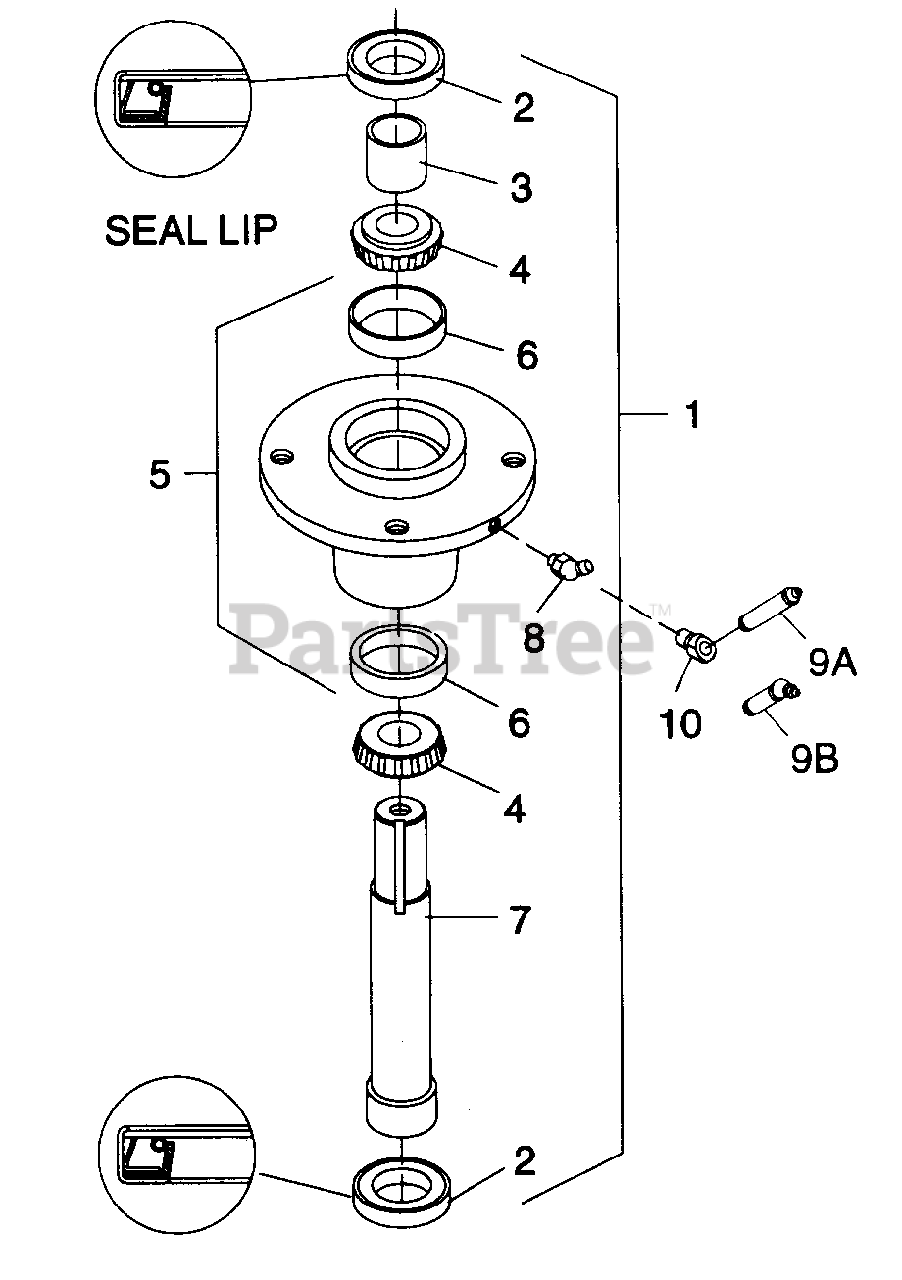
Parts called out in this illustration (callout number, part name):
1	CW Blade spindle assembly
2	Seal, 1.063 x 2.004 x .265
3	Sleeve, .843 x 1.063 x .812
4	Bearing cone #M12649
5	Spindle housing with cups
6	Bearing cup #M12610
7	Spindle shaft, Right hand threads
8	1/4 Tapered thread 45ø grease fitting
9A	1/8M PTF x 1.75 Grease fitting for center spindle
9B	1/8 NPT 30ø x 2.09 Grease fitting for right and left spindles
10	1/8F x 1/4-28M 45ø Grease fitting
